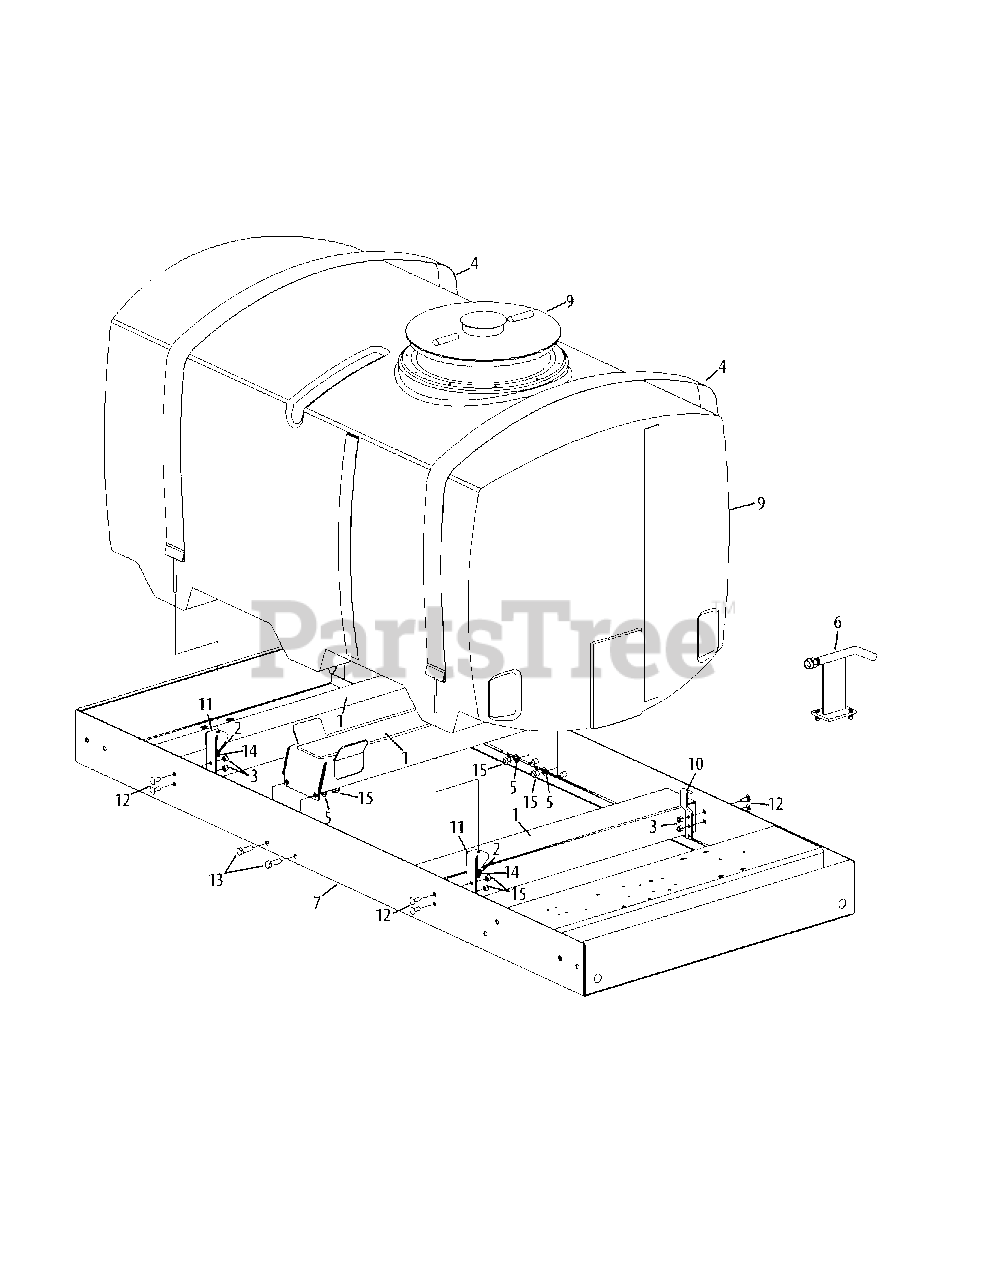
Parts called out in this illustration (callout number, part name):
1	Adhesive Backed Foam
2	Flat Washer, 5/16
3	Lock Nut, 3/8-16
4	Tank Strap
5	Flat Washer, .536 x .930 x .05
6	Air Gap Filler
7	Main Frame
7	Center Support Bracket
9	300 Gallon Poly Tank
10	Strap Mounting Hook
11	Strap Mounting Bracket
12	Carriage Bolt, 3/8-16 x 1.00
13	Hex Screw, 1/2-13 x 1.50
14	Hex Lock Nut, 5/16-18
15	Hex Lock Nut, 1/2-13
